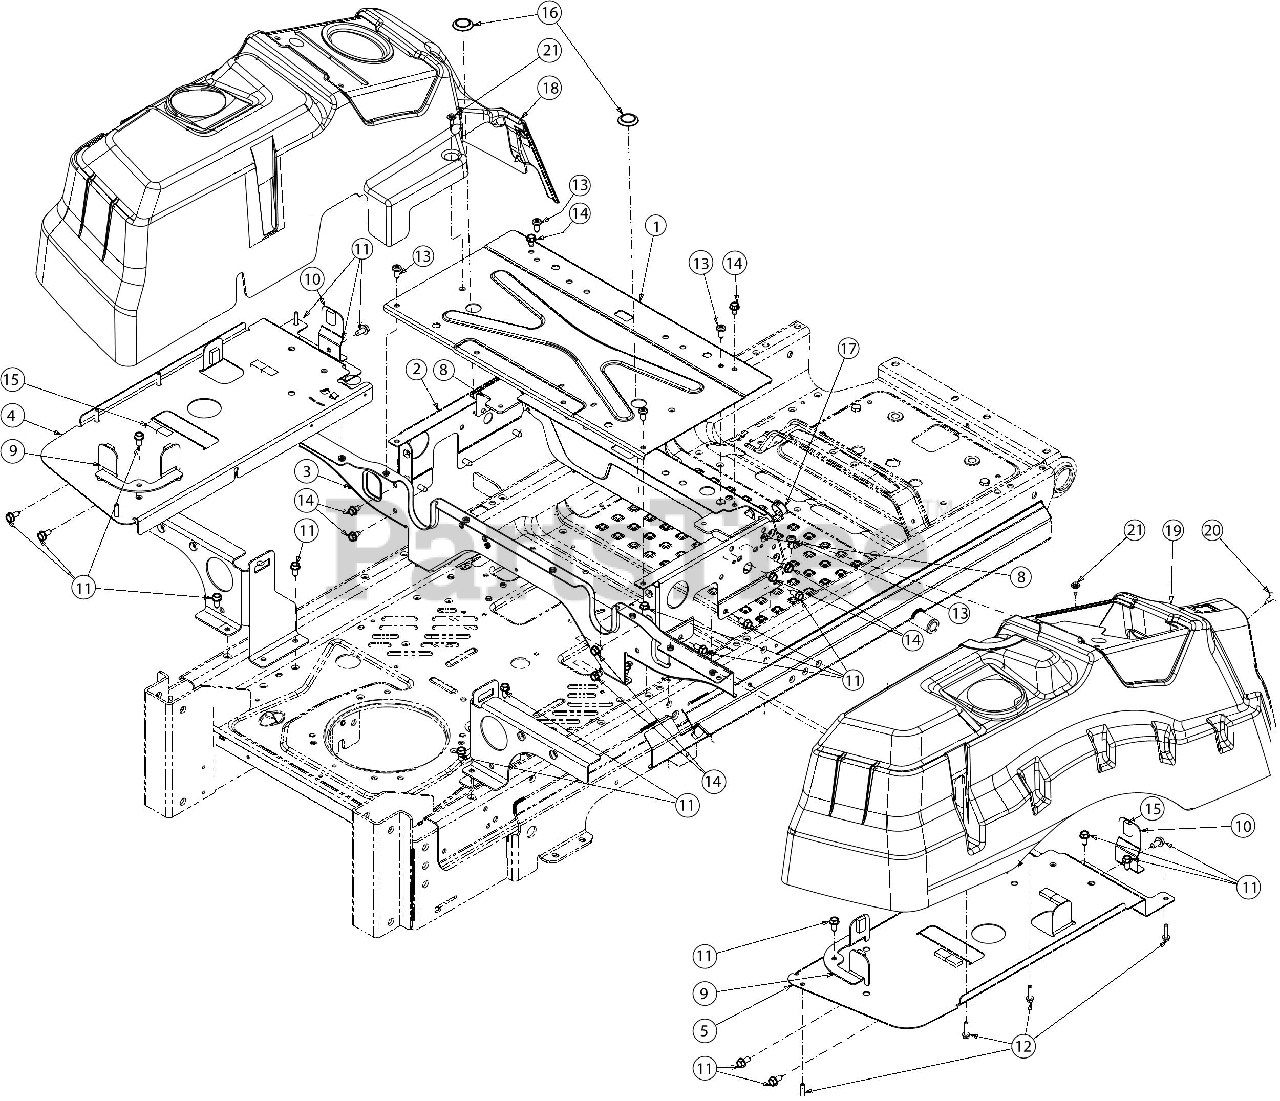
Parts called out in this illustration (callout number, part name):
1	SEATBOX TOP PLATE
2	SEAT FRAME
3	REAR SEATBOX BRACE
4	TANK SUPPORT PLATE (LH)
5	TANK SUPPORT PLATE (RH)
6	REAR BRACKET SUPPORT (LH)
7	REAR BRACKET SUPPORT (RH)
8	SEAT BOX BRACKET
9	REAR TANK BRACKET
10	FRONT TANK BRACKET
11	SCREW 5/16-18 X .750
12	SCREW 5/16-14 X 1
13	SCREW 5/16-18 X .750
14	SCREW 5/16-18 x .500
15	FOAM TAPE .625 WIDE X .25 THK BULK
17	PLASTIC PLUG
18	CONSOLE (LH) Z-STYLE
19	CONSOLE (RH) Z-STYLE
20	TORX SHOULDER SCREW 1/4-20
21	SHOULDER SCREW M6-1 .368 X.115
